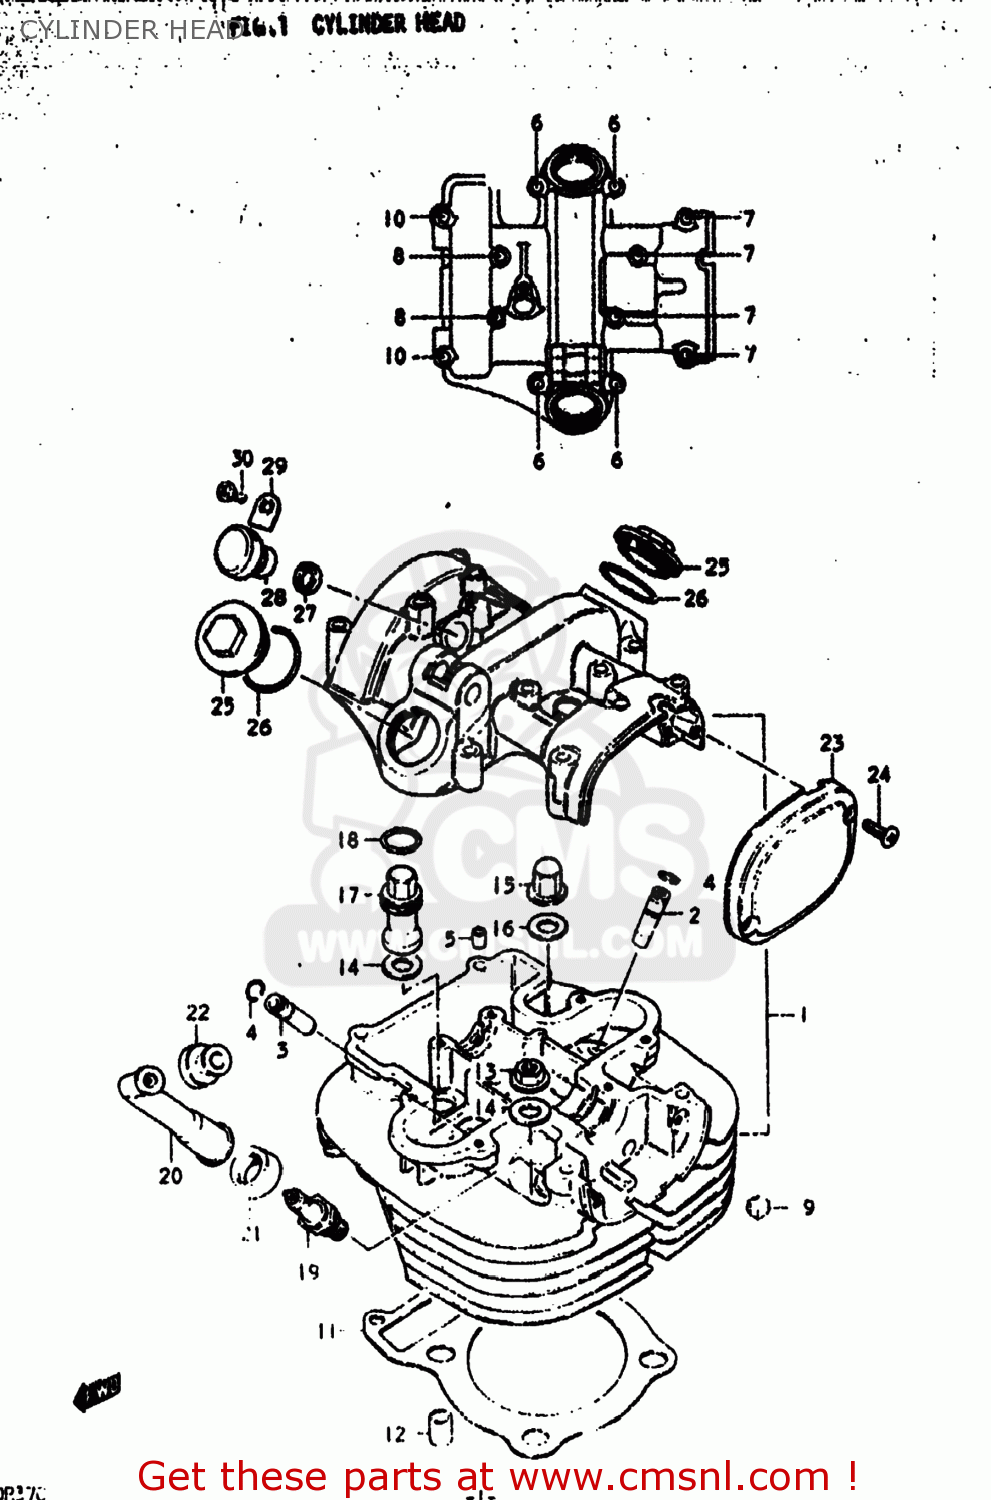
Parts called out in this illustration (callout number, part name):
1	HEAD ASSEMBLY,CYLINDER
2	GUIDE,VALVE
3	GUIDE,VALVE
4	RING,SNAP
5	PIN(6.2X8X11)
6	BOLT 6X35
7	BOLT ,6X50
8	BOLT 6X65
9	PAD
10	BOLT
11	GASKET,CYLINDER HEAD (NAS)
12	PIN
13	NUT
14	WASHER(10.5X22X2.3)
15	NUT
16	GASKET(10.5X22X2) (NAS)
17	NUT,CYLINDER HEAD SEAL
18	O RING(D:2.4,ID:17.8)
19	SPARK PLUG D8EA
20	CAP ASSY,SPARK PLUG
21	SEAL,SPARK PLUG
22	SEAL,SPARK PLU
23	CAP,CONTACT BREAKER
24	SCREW
25	CAP,INSPECTION
26	O RING(D:3,ID:29.5)
27	SEAL,TACHOMETER DRIVEN
28	PLUG,TACH GEAR SLEEVE HOLE
29	PLATE,TACH DRIVE GEAR SLEEVE
30	SCREW(5X12)
